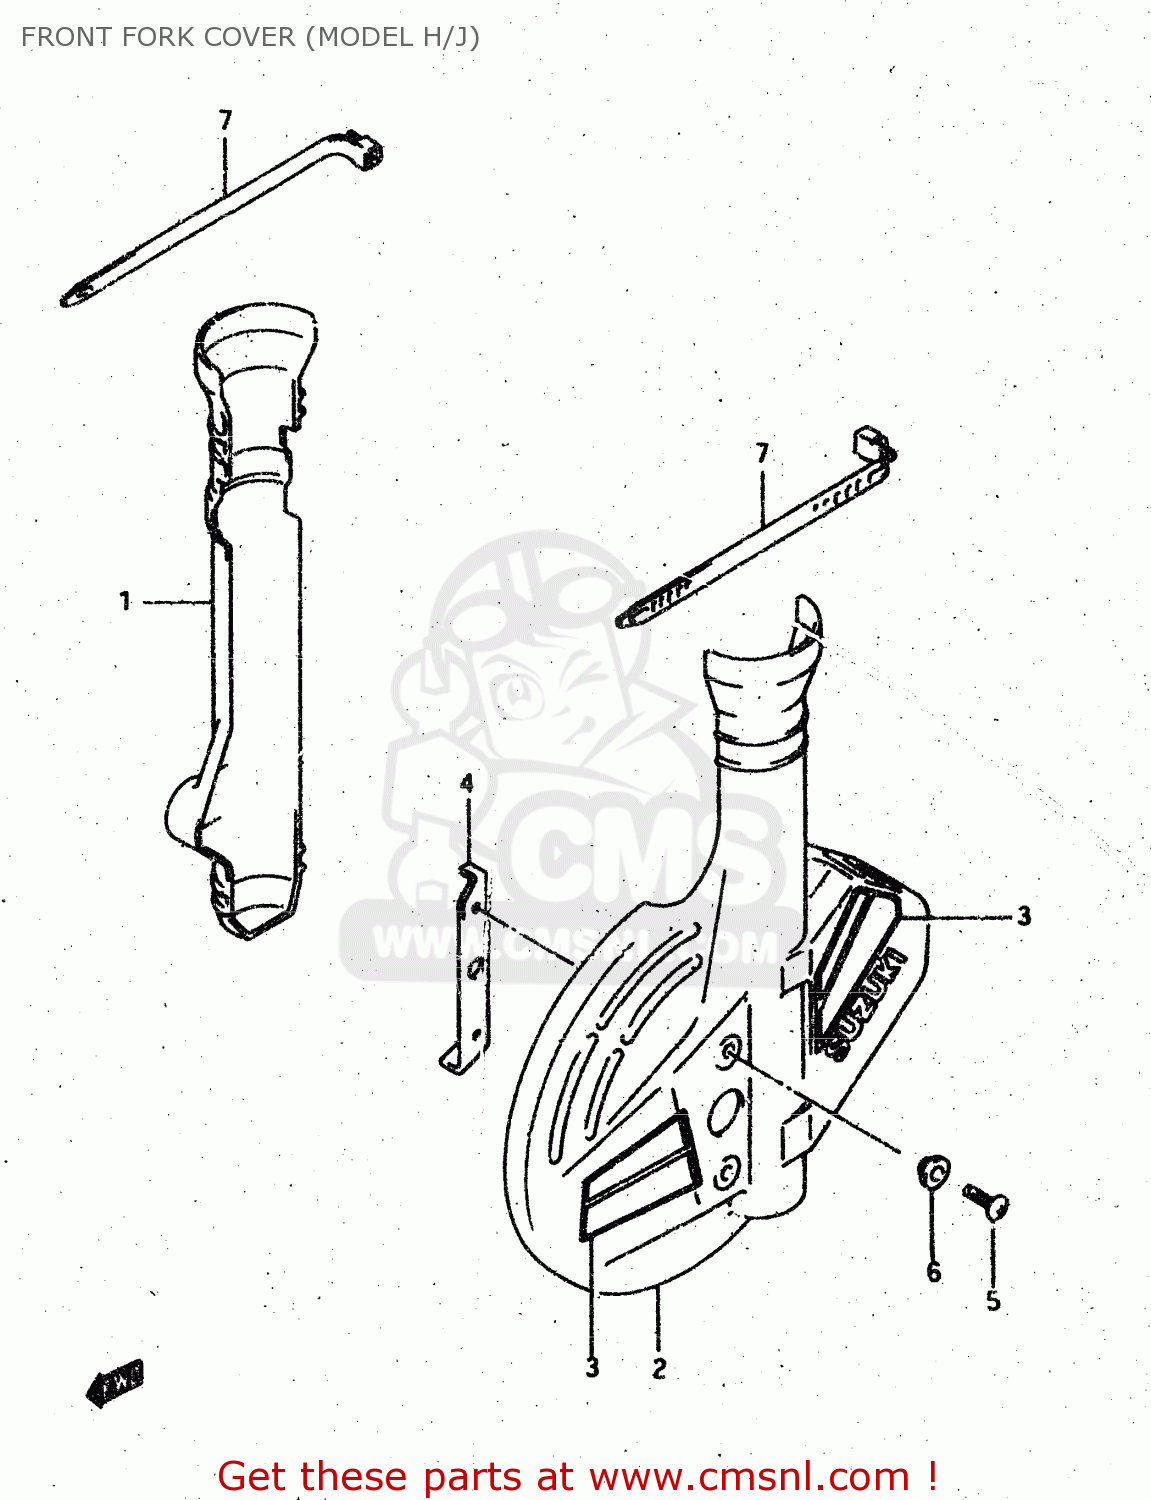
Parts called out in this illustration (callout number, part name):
1	PROTECTOR, FRONT FORK RH
2	PROTECTOR, FRONT FORK LH
3	TAPE SET, PROTECTOR
4	PLATE, PROTECTOR SET
5	SCREW 6X12
6	WASHER
7	CLAMP
